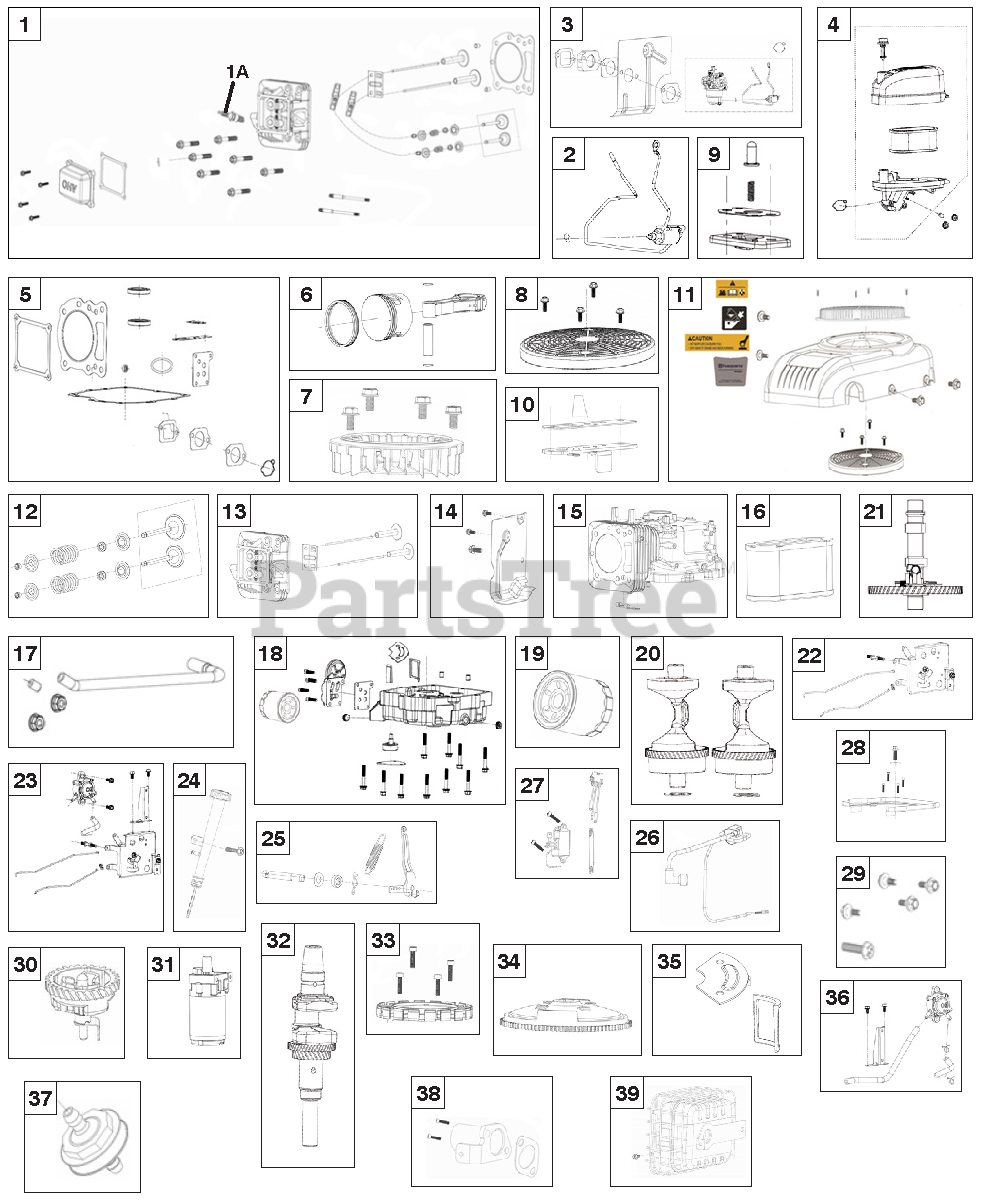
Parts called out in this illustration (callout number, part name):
1	SERVICE KIT CYLINDER HEAD COM
1A	SPARK PLUG
2	SOLENOID KIT
3	SERVICE KIT CARBURETOR,KIT. TR
4	SERVICE KIT KIT.AIR.CLEANER/60
5	SERVICE KIT GASKET.SEAL KIT
6	SERVICE KIT PISTON AND RING SE
7	SERVICE KIT FAN COOLING AND FA
8	SERVICE KIT KIT.FAN.COOLING.CO
9	SERVICE KIT REEED VALVE KIT
10	SERVICE KIT VALVE BREATHER KIT
12	SERVICE KIT KIT.VALVE (KIT 12)
13	SERVICE KIT KIT.CYLINDER.HEAD.
14	SERVICE KIT KIT.AIR.DEFLECTOR
15	SERVICE KIT KIT.CRANKCASE.BODY
16	AIR FILTER AIR FILTER.608
17	Poulan TBD
18	SERVICE KIT KIT.CRANKCASE.COVE
19	SERVICE KIT KIT.OIL.FILTER (KI
20	SERVICE KIT KIT.CRANKSHAFT.BAL
21	CAMSHAFT KIT
22	SERVICE KIT KIT.THROTTL.LEVER
23	SERVICE KIT KIT.THROTTLE.LEVER
24	SERVICE KIT FILL TUBE KIT W/FU
25	SERVICE KIT KIT.SPEED.REGULATI
26	SERVICE KIT KIT.IGNITION.COIL
27	SERVICE KIT KIT.VOLTAGE.RECTIF
28	SERVICE KIT KIT.SIDE.PLATE (KI
29	SERVICE KIT KIT.BOLT. (KIT 30)
30	SERVICE KIT KIT.GOVENOR.GEAR.
31	SERVICE KIT KIT.STARTER.MOTOR
32	SERVICE KIT KIT.CRANK.SHAFT
33	SERVICE KIT KIT.CHARGING.ARMAT
34	SERVICE KIT KIT.FLYWHEEL
35	SERVICE KIT KIT.OIL.STRAIN
36	MODULE KIT.FUEL.SYSTEM
38	SERVICE KIT KIT.EXHAUST.PIPE (
